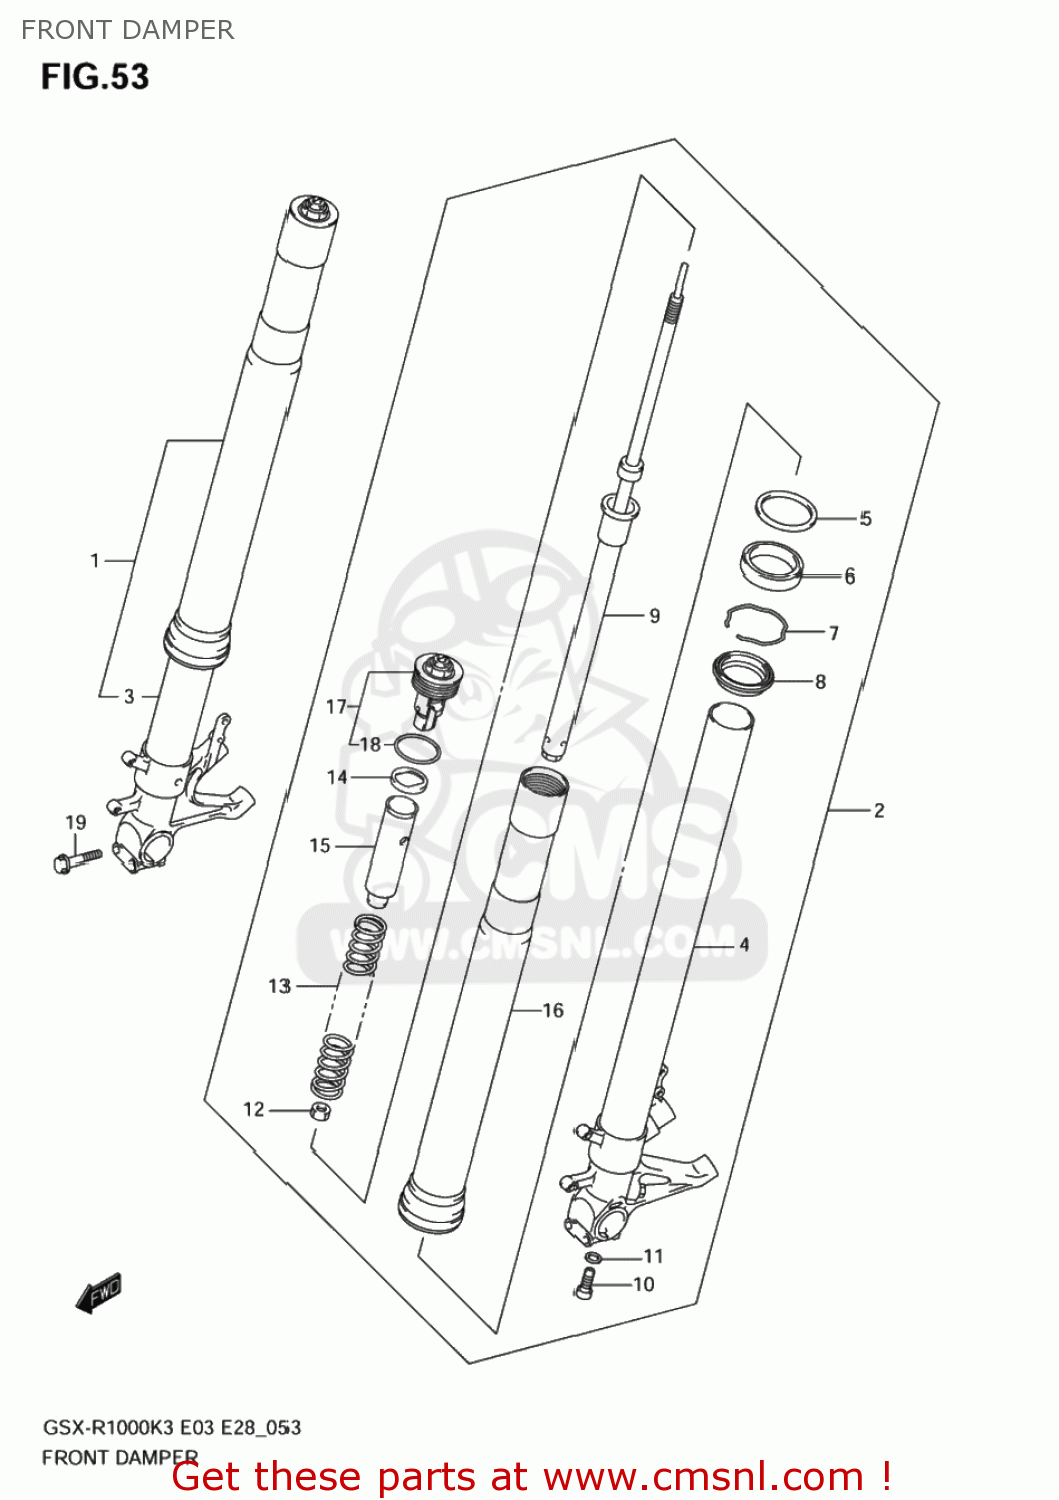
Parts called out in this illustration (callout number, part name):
1	DAMPER ASSY,FR FORK,R
2	DAMPER ASSY,FR FORK,L
3	TUBE,INNER,R
4	TUBE,INNER,L
5	WASHER
6	SEAL,OIL
7	RING,STOPPER
8	SEAL,DUST
9	CYLINDER
10	BOLT
11	GASKET (NAS)
12	NUT
13	SPRING,FR
14	GUIDE,SPRING
15	SPACER,SPRING
16	TUBE,OUTER
17	CAP,FR FORK
18	O RING
19	BOLT
